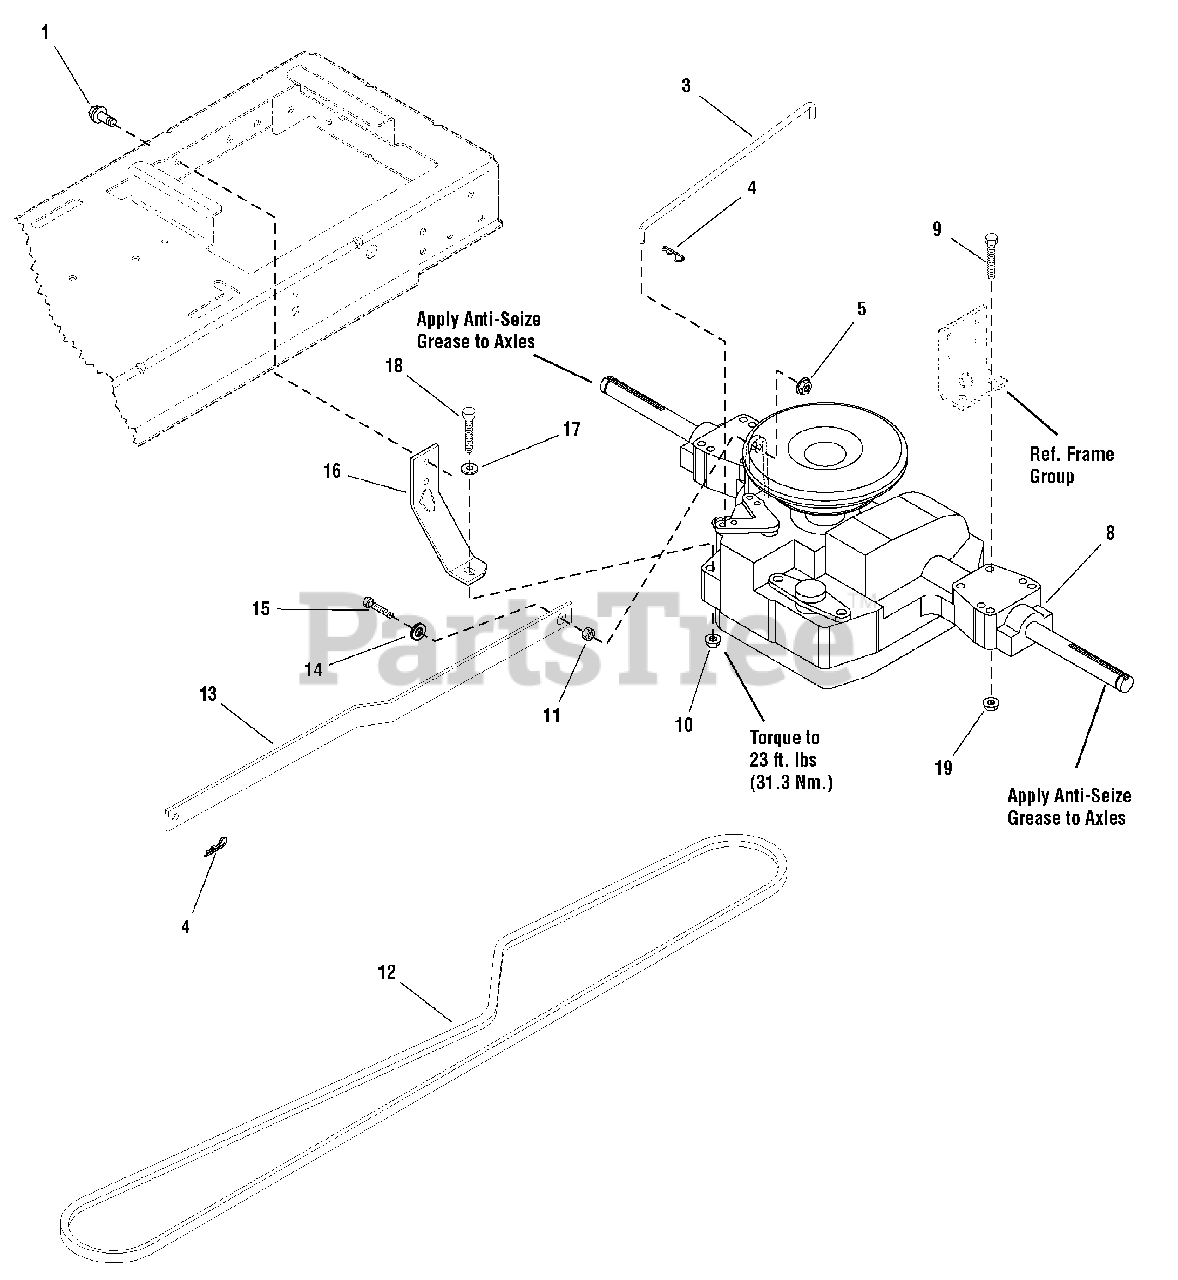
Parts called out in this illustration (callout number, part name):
1	CAPSCREW, Hex Head, Taptite, 5/16-18 x 3/4
3	ROD, Bypass, 11.44 LG Yellow
4	PIN, Quick
5	NUT, Hex Flange, 5/16-18 ESNA
8	* TRANSMISSION ASSEMBLY, K46BP
8	* TRANSMISSION, Tuff Torq K46BL
9	SCREW, Hex Head Flange Lock, 5/16-18 x 2-1/2
10	NUT, Hex Flange, 5/16-18 ESNA
11	SPACER
12	V-BELT, Drive Belt, Aramid/Kevlar
13	ARM, Control
14	WASHER, Flat, 5/16
15	CAPSCREW, Hex Head, 5/16-18 x 1
16	STRAP, Torque 7 GA
17	WASHER, Plain, 5/16
18	CAPSCREW, Hex Head, 5/16-18 x 1-3/4
19	NUT, Hex Flange, Whiz Lock, 5/16-18
